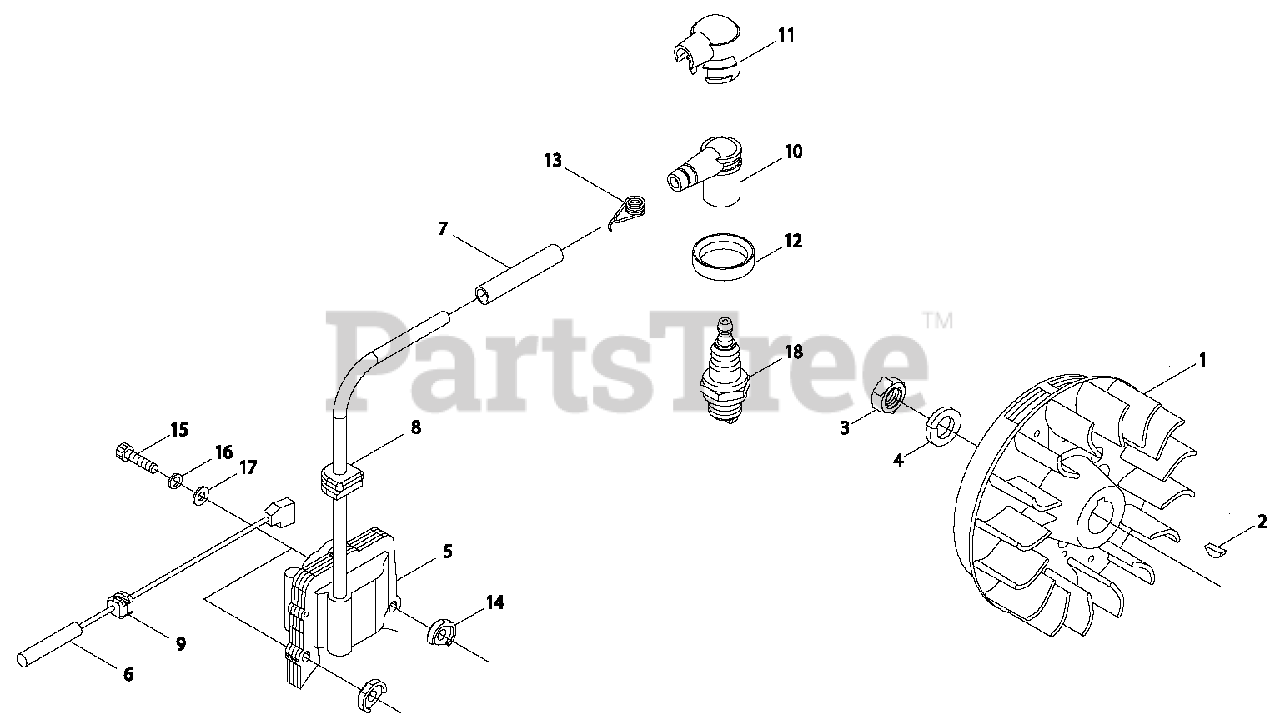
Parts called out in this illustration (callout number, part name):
1	FLYWHEEL
2	KEY - 3X10
3	NUT - 10
4	LOCKWASHER - 10
5	COIL, IGNITION
6	LEAD - IGNITION
7	TUBE
8	GROMMET
9	GROMMET
10	CAP, SPARK PLUG
11	COVER, CAP
12	SEAL, DUST
13	TERMINAL, SPARK PLUG CAP
14	INSULATOR
15	BOLT - 4X24
16	LOCKWASHER - 4
17	WASHER
18	SPARK PLUG -- CJ-8
